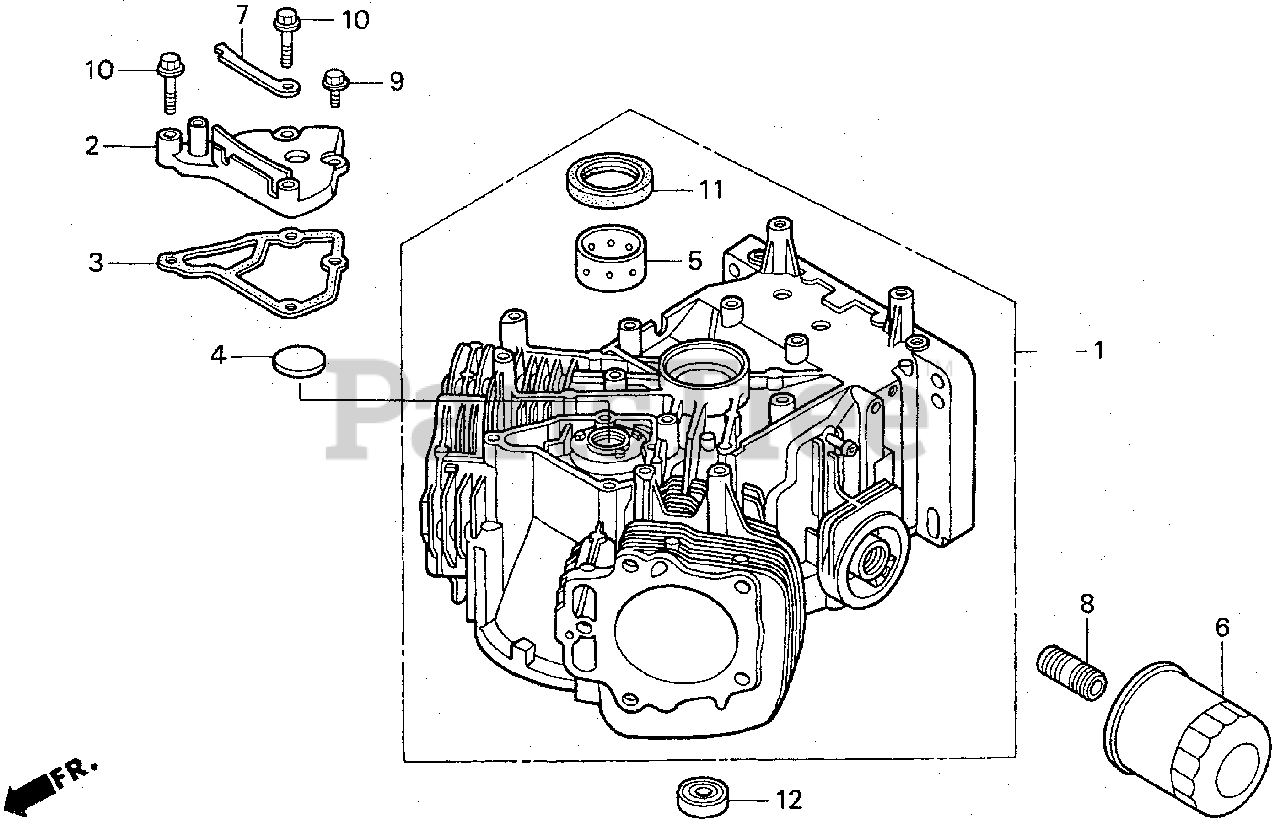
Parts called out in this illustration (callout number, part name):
1	CYLINDER ASSY.
2	COVER, BREATHER
3	GASKET, BREATHER COVER
4	VALVE, BREATHER
5	BEARING A, MAIN
5	BEARING B, MAIN
5	BEARING C, MAIN
6	FILTER, OIL (FILTECH TOYO ROKI) (SOLD INDIVIDUALLY)
6	FILTER, OIL (SOLD INDIVIDUALLY)
7	CLAMP, WIRE
8	HOLDER, OIL FILTER
9	BOLT, FLANGE (6X16)
10	BOLT, FLANGE (6X32)
11	OIL SEAL (38X58X11)
12	BEARING, RADIAL BALL (6003)
